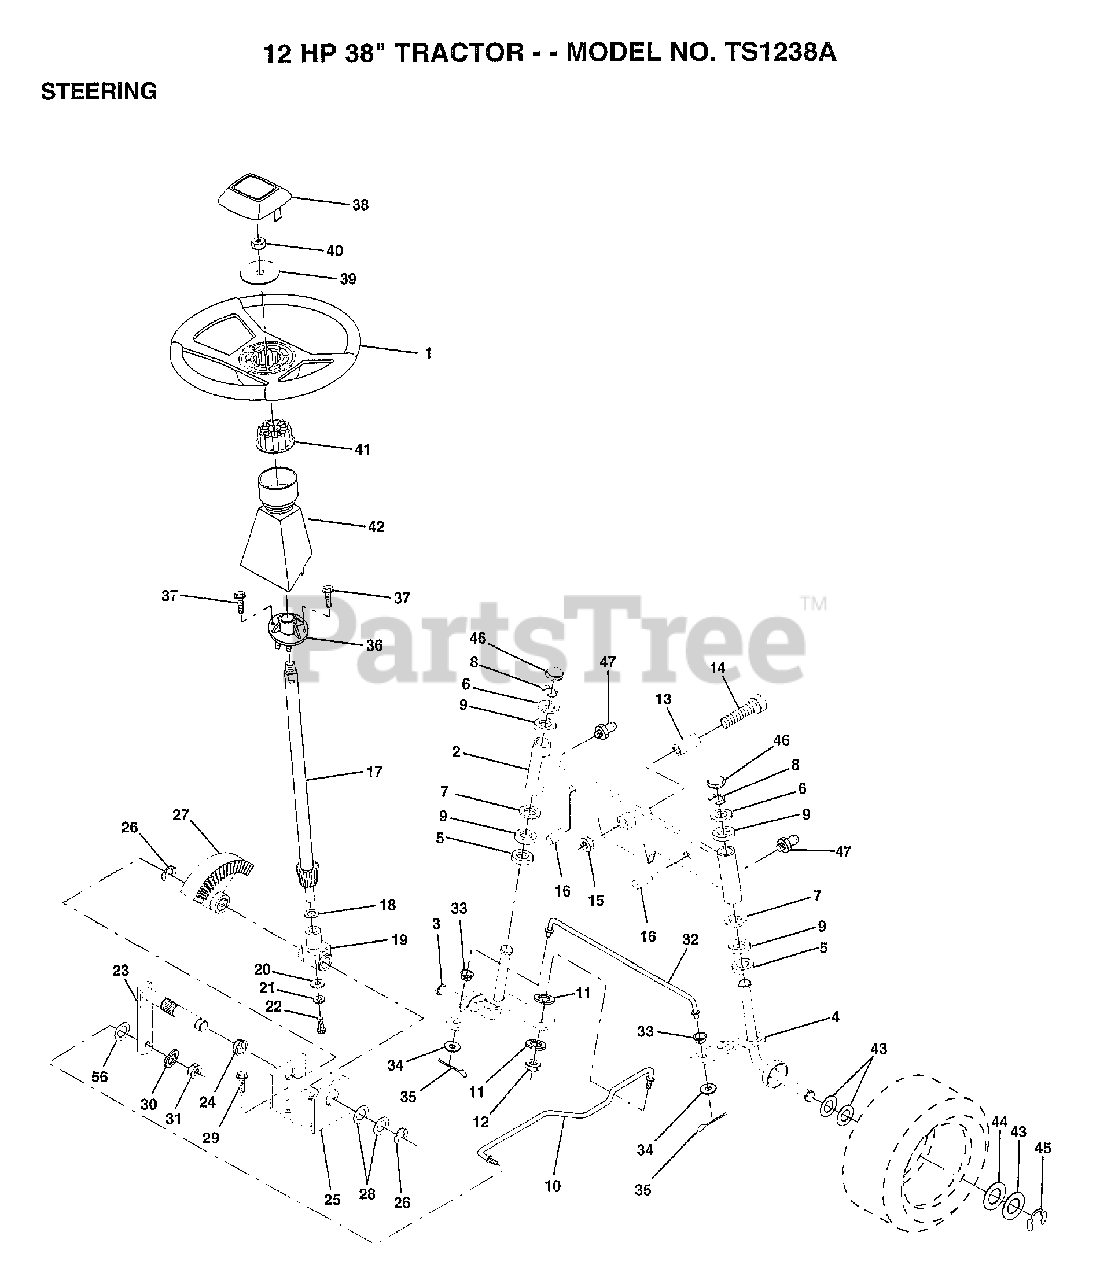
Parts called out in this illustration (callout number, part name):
3	SPINDLE LH
4	SPINDLE RH
5	WASHER .T
6	WASHER
7	WASHER
8	RING
9	COL. SRTG. BEAR.
11	LOCKWASHER
13	BEARING
14	BOLT HEX 5/8-11
15	"NUT-LOC,FLANGE LT"
16	AXLE PIN
17	SHAFT ASM
18	THRUST WASHER
19	SUPPORT.SHAFT
21	LOCKWASHER
22	"SCREW,SPECIAL"
24	NYLINER T
25	"BRKT,STEERING"
26	RING
27	GEAR SECTOR
28	WASHER .T
29	SCREW
30	LOCKWASHER
32	TIE ROD
33	BUSHING.DRAGLINK
34	WASHER
35	COTTER PIN
38	ST WHL INSERT CAP
39	WASHER T
40	GRIPCO NUT
41	ADAPTER-WHEEL LT
42	"TUBE, STR SHAFT"
43	WASHER
44	WASHER
45	RING
46	CAP
47	ZERK M
56	WASHER
